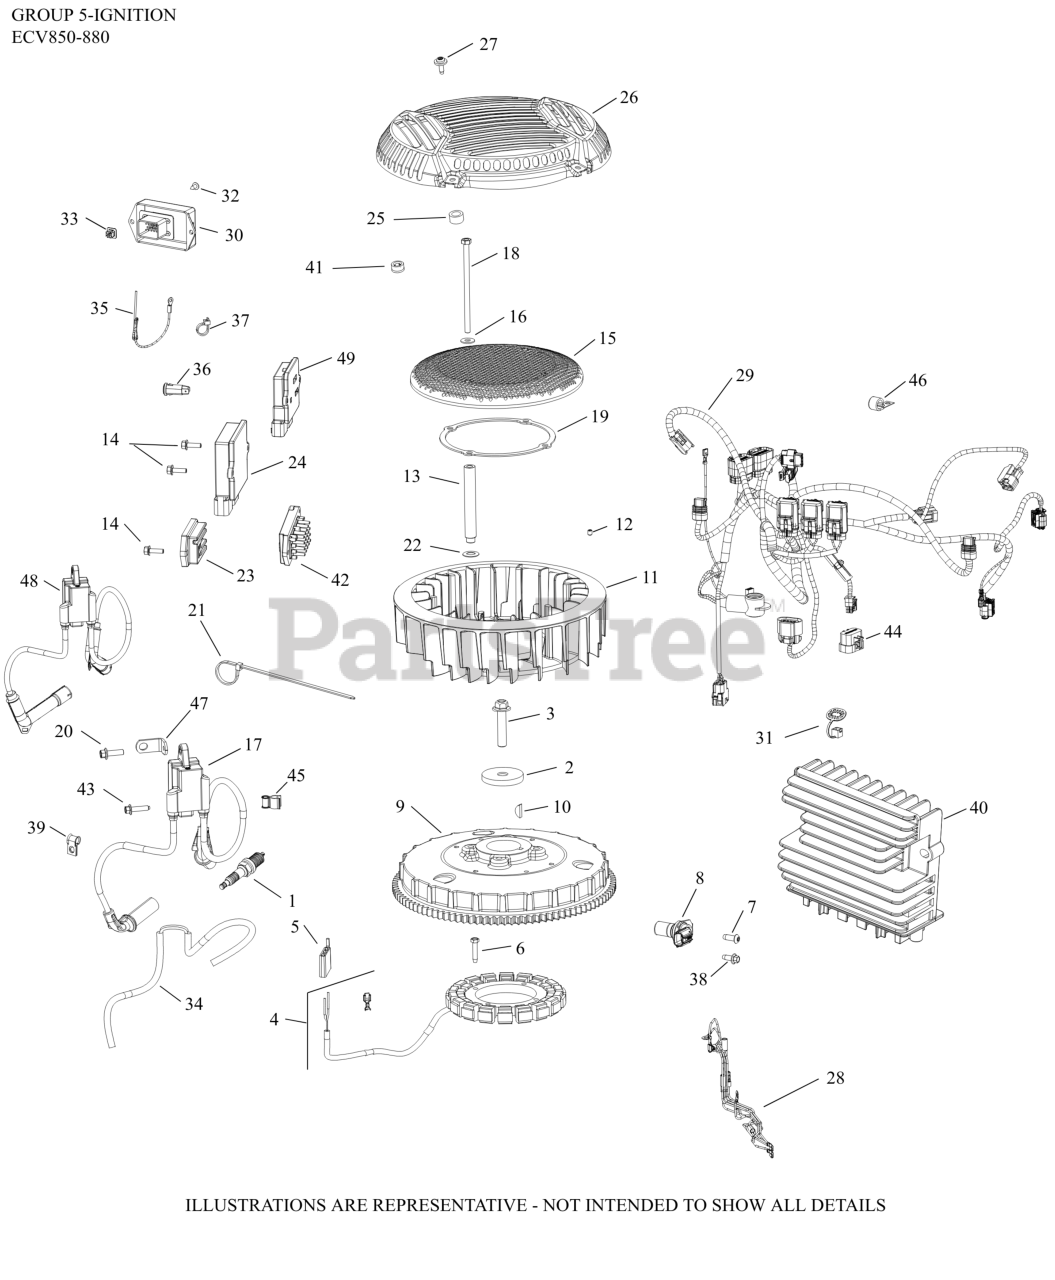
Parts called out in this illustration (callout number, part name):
1	PLUG, SPARK
2	WASHER, FLAT 13/32"
3	SCREW, FLG M10X1.5X45-USE 25 086 361-S
4	KIT, 25 AMP STATOR ASSY.
5	CONNECTOR
6	SCREW, THREAD FORMING
8	SENSOR, SPEED
9	FLYWHEEL, ASSEMBLY
10	KEY, 3/16" X 5/8"
11	FAN
12	SCREW, SKT SET #10-24X1/4"
13	SPACER GRASS SCREEN
14	SCREW, HVY FLG M5X.8X16
15	SCREEN, GRASS
16	WASHER, SPRING 10 MM
17	COIL, IGNITION DUAL OUTPUT
18	SCREW, HEX HEAD
19	RING, SUPPORT
20	SCREW, FLG M6x1.0x20
22	WASHER, FLAT 1/4" (O.D. 5/8")
24	MODULE, ECU
26	GUARD, GRASS SCREEN (METAL)
27	SCREW, SEMS
29	HARNESS, WIRING ASSEMBLY - EFI
31	CAP, CONNECTOR
38	SCREW, THREAD FORMING
42	REGULATOR, RECT (20-30AMP, FW W/OVP)
NI	CLIP, CABLE (KM)
